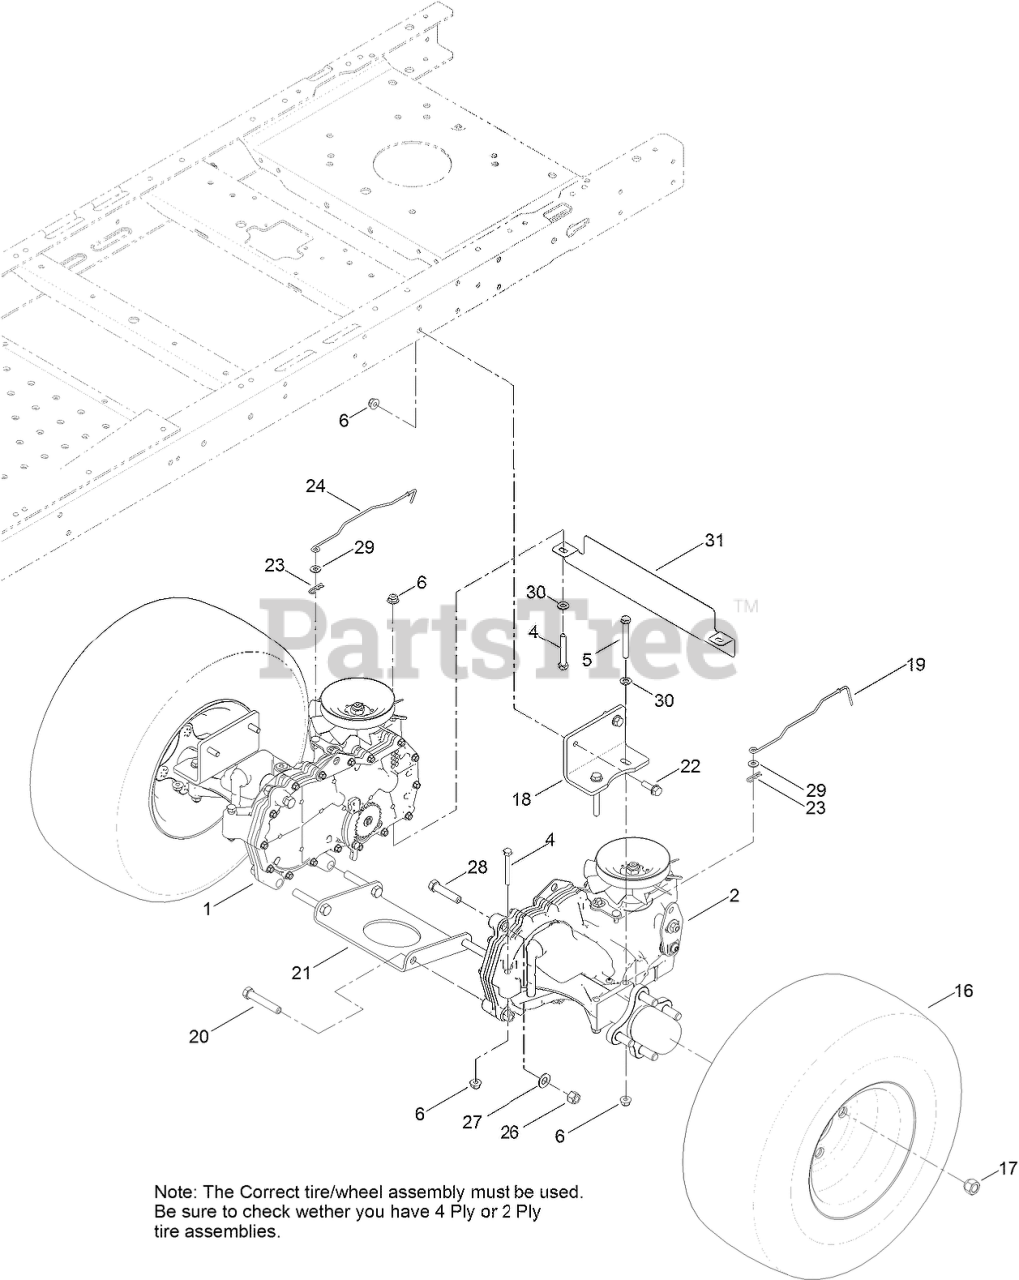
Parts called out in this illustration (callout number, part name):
1	RH HYDRO TRANSAXLE ASM
2	LH HYDRO TRANSAXLE ASM
4	SCREW-HH
5	SCREW-HH
6	NUT-HF, NI
16	4 PLY WHEEL AND TIRE ASM
16	2 PLY WHEEL AND TIRE ASM
17	NUT-LUG
18	MOUNT-HYDRO
19	ROD-BYPASS, LH
20	SCREW-HH
21	PLATE-CROSS, HYDRO
22	SCREW-HHF
23	PIN-COTTER
24	ROD-BYPASS, RH
26	NUT-LOCK, NI
27	WASHER-FLAT
28	SCREW-HH
29	WASHER
30	WASHER-PLAIN
31	GUARD REAR, WIDE
